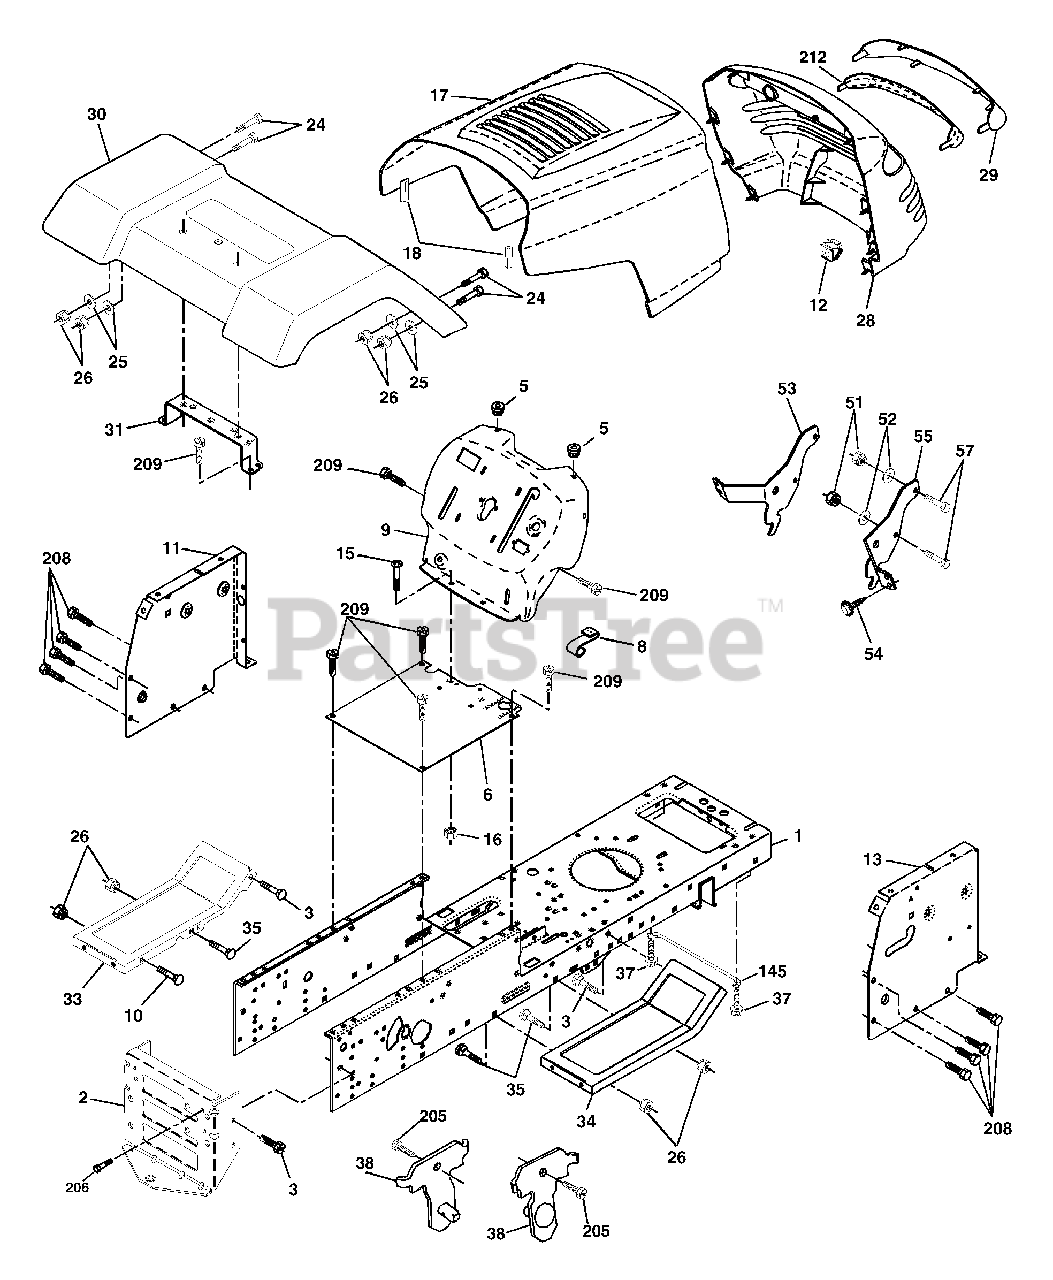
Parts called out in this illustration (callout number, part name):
1	Chassis
2	Drawbar, Stretch
3	Screw 3/8-16 x 3/4
5	Bumper, Hood/Dash
6	Saddle Silkscreen
8	Clip Retainer Slide-On
9	Dash
10	Bolt, Carriage 3/8-16 x 1
11	Panel Dash LH
12	Clip Tinnerman Grille P.L
13	Panel Slkscr Dash RH
15	Screw Mach TRHD 5/16-18uncx3/4
16	Nut Keps 5/16-18 Unc
17	Hood
18	Bumper Hood
24	Bolt Fin Hex 3/8-16unc X 1 Gr. 5
25	Washer 13/32 X 13/16 X 12 Ga
26	Nut Lock Hex w/Ins 3/8-16 Unc
28	Grille/Lens Asm.
29	Lens Grille Private Label
31	Bracket Fender Repl 109873x
33	Footrest Pnt LH
34	Footrest Pnt RH
35	Bolt Rdhd Sht Sqnk 3/8-16 X3/4
37	Screw Thdrol 5/16-18 x 1/2 TYT
38	Bracket Asm. Pivot Mower
51	Nut Lock W/Insert 1/4-20unc
52	Washer 9/32 x 7/8x16 Ga.
53	Bracket Grille Lh
54	Screw Hex 8-18 x 7/8
55	Bracket Grille Rh
57	Bolt Fin Hex 1/4-20 unc x .75
145	Rod Pivot Chassis/Hood
205	Screw Thdrol 3/8-16 x 1/2
206	Bolt Shoulder 5/16-18
208	Screw Thdrol 3/8-16 x 1/2
209	Screw Hex Wsh Thdrol 3/8-16
212	Insert Lens Reflect
